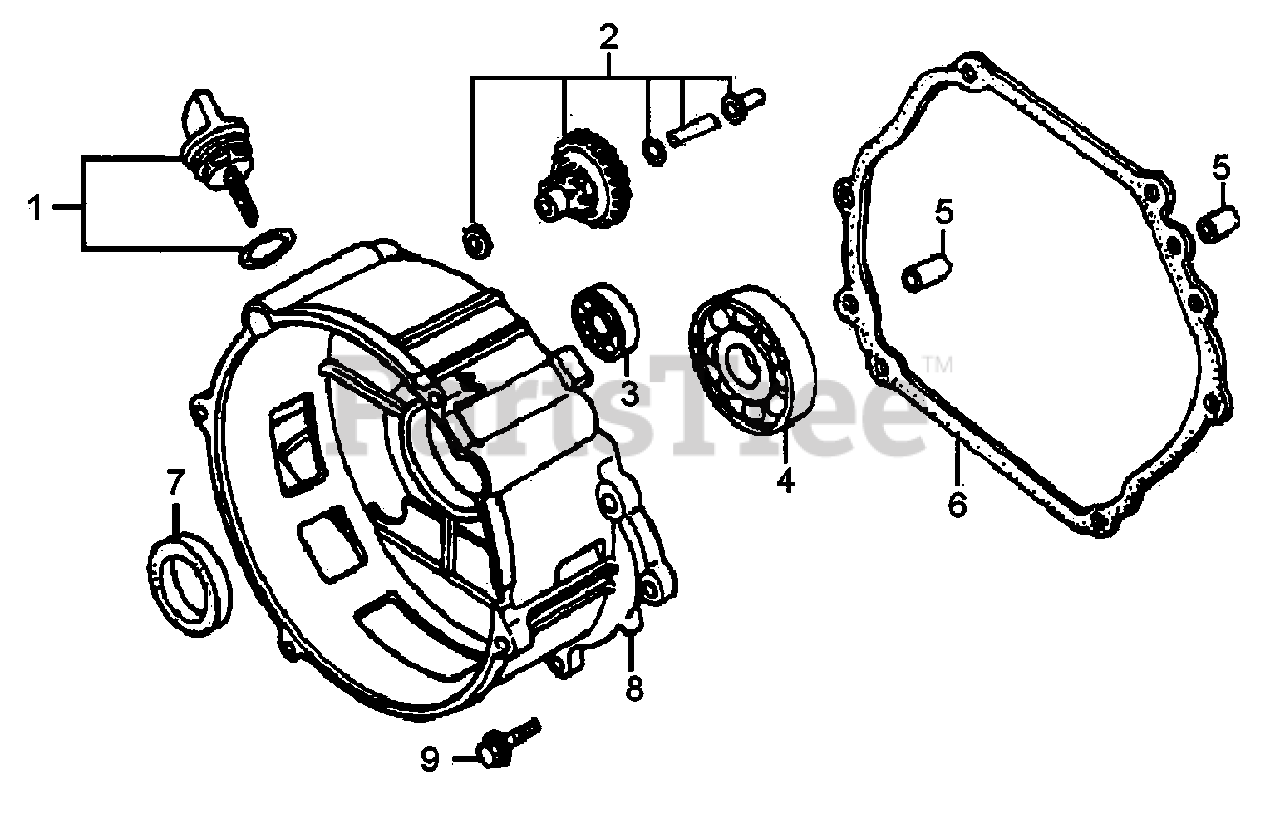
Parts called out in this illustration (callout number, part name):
1	CAP ASSY., OIL FILL
2	GOVERNOR ASSY.
3	BEARING, RADIAL BALL 6202
4	BEARING, RADIAL BALL 6207
5	DOWEL PIN 8x12
6	GASKET, CRANKCASE COVER
8	CRANKCASE COVER
9	BOLT, FLANGE 8X40
